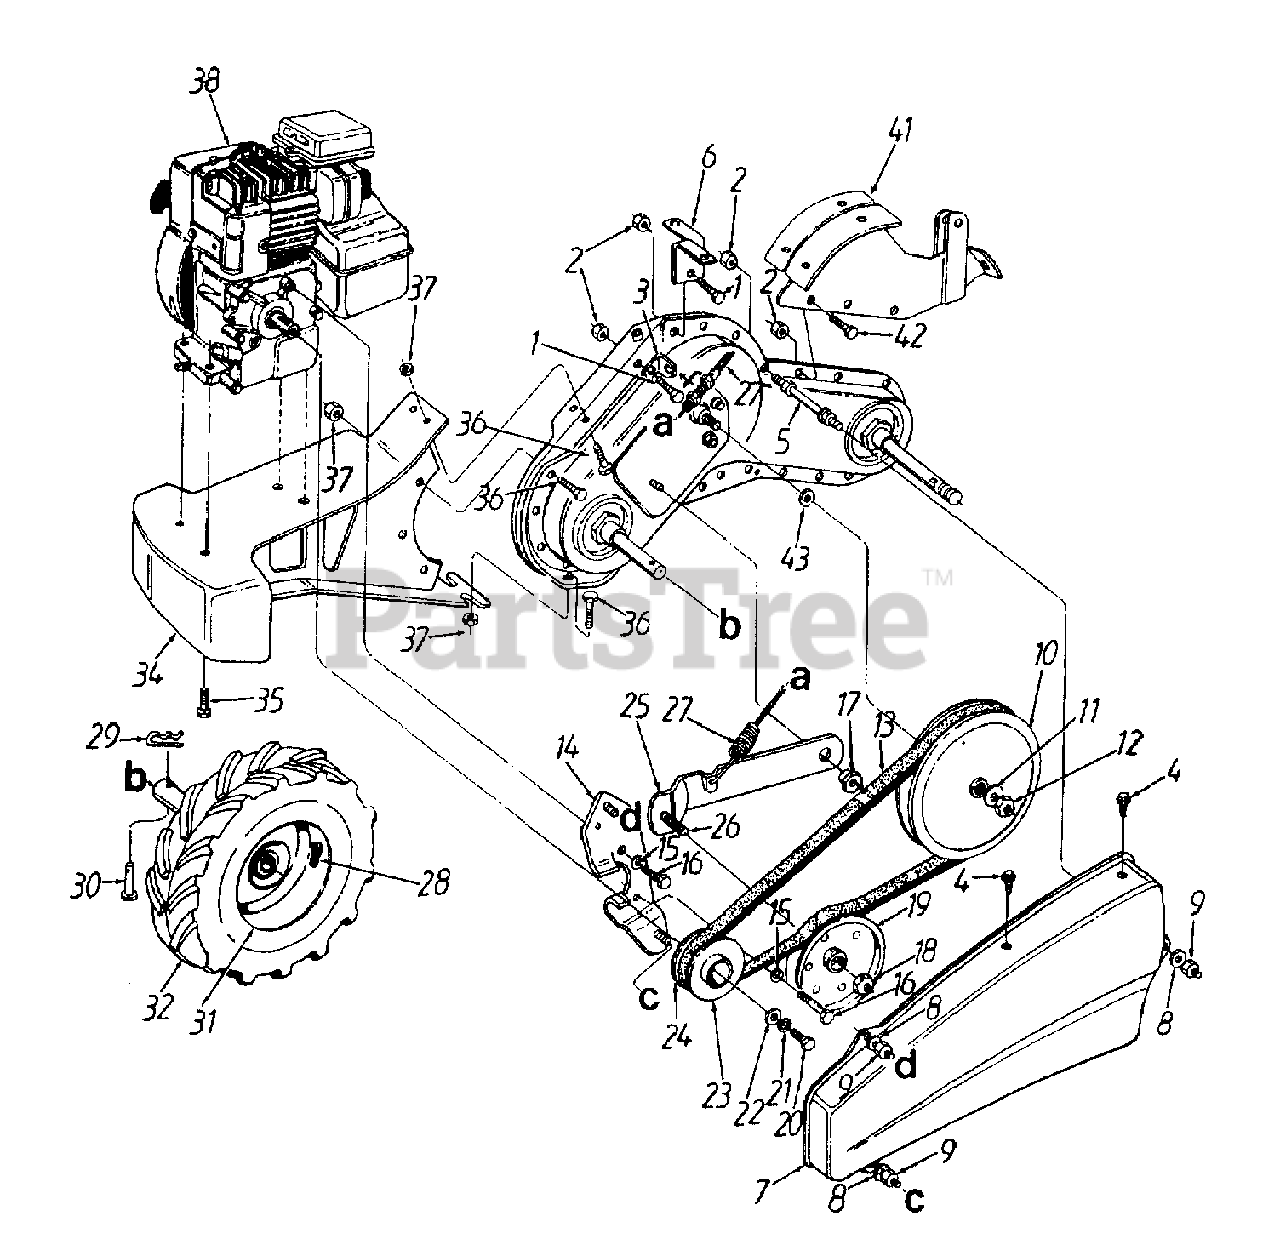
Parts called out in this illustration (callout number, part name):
1	Hex Bolt 5/16-18 x .75" Lg.
2	Hex Top L-Nut 5/16-18 Thd.
3	Cable Mtg. Bracket
4	Torx Mach. AB-Tap Scr. 1/4 x .6" Lg
5	Belt Cover Bolt
9	Hex Cap Nut 1/4-28 Thd.
10	Flat Pulley 8" O.D.
11	Bell-Wash. .38" I.D. x .88" O.D.
12	Hex Flange Nut.
13	" V"-Belt
16	Hex Bolt 5/16-24 x .62" Lg.
17	Shld. Nut
18	Hex Jam L-Nut 3/8-16 Thd.
19	Fl-Idler w/Flanges
20	Hex Bolt 3/8-24 x 1" Lg.
21	L-Wash. 3/8" I.D.
22	Fl-Wash. 3/8" I.D. x 1" O.D.
23	Outer Engine Pulley Half
24	Inner Engine Pulley Half
26	Hex Bolt 3/8-16 x 1.25" Lg.
27	Clutch Cable
28	Air Valve
29	Hairpin Clip
30	Clevis Pin
34	Frame Counterweight
35	Hex TT Tap Scr. 3/8-16 Thd.
36	Hex Bolt 5/16-18 x 1" Lg. (Gr. 5)
37	Hex Flange L-Nut 5/16-18 Thd.
38	Engine
43	Wash. FL. .635 I.D. x .930 0.D. x .03
